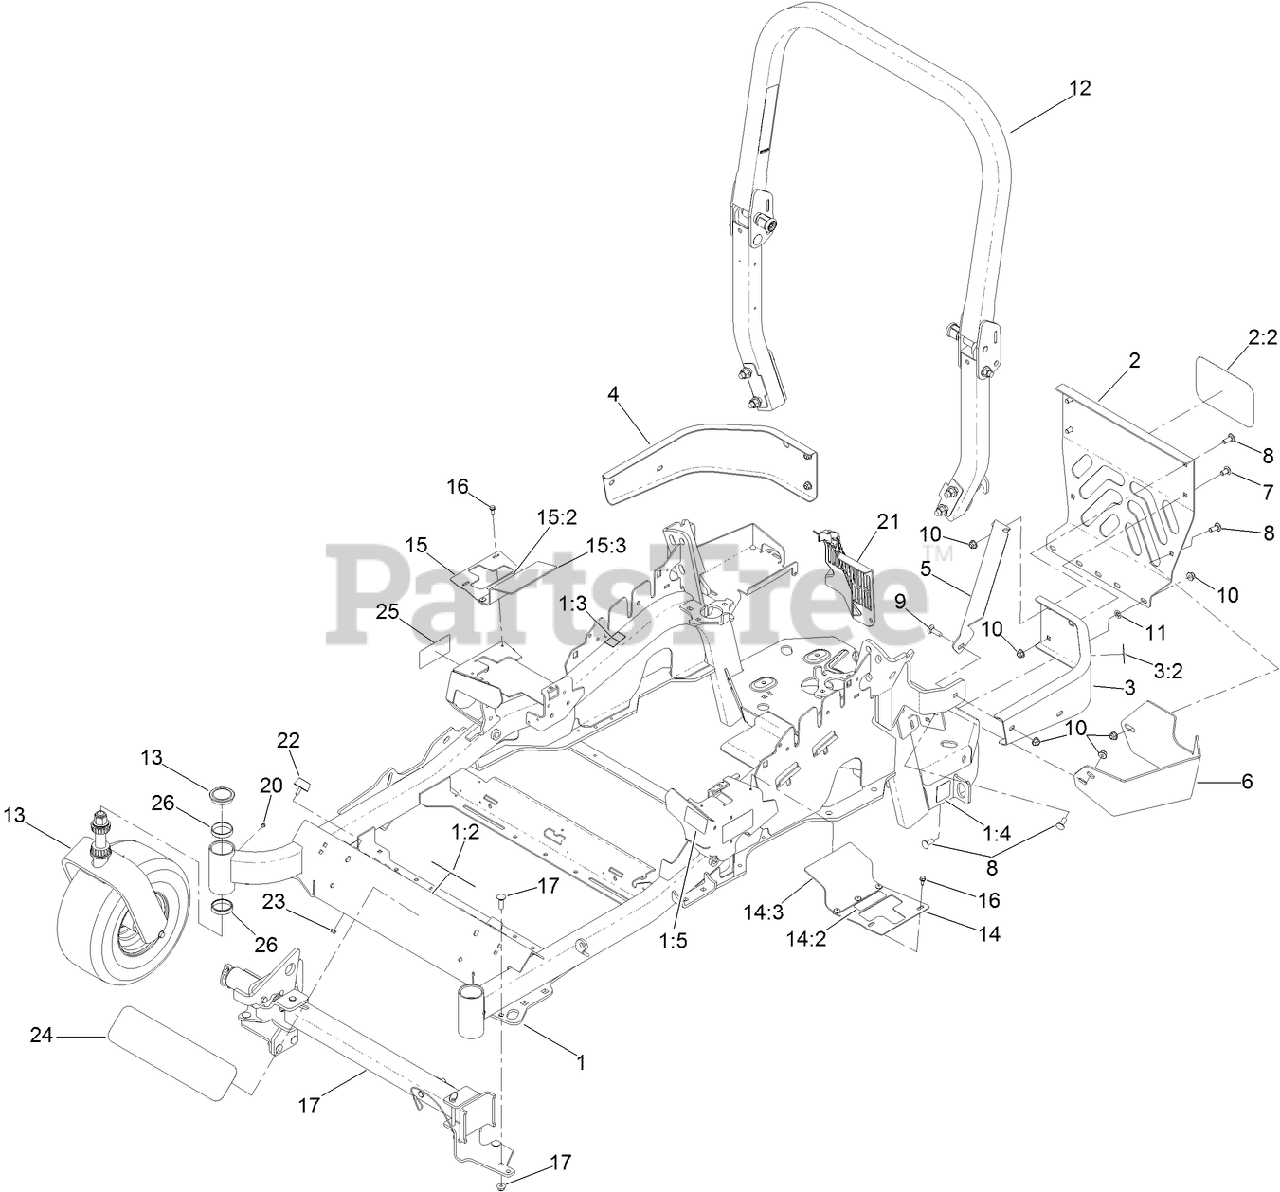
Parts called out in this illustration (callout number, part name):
1	MAIN FRAME ASM
1:2	DECAL-DANGER
1:3	DECAL-WARNING
1:4	DECAL-HAZARD, PINCHED FINGER
1:5	DECAL-FUEL FILL, CE
2	REAR GUARD ASM
2:2	DECAL
3	LH REAR BUMPER ASM
3:2	DECAL-WARNING
4	BUMPER-RH
6	GUARD-MUFFLER
7	SCREW-CARR
8	SCREW-CARR
9	BOLT-CARR
10	NUT-HF, NI
11	NUT-PUSH
12	ROPS ASM
13	Caster Wheel ASM
14	LH MOTION CONTROL COVER ASM
14:2	DECAL-CONTROL, MOTION
14:3	FLAP-RUBBER
15	RH MOTION CONTROL COVER ASM
15:2	DECAL-CONTROL, MOTION
15:3	FLAP-RUBBER
16	SCREW-HWH
17	Z STAND ASM
21	GUARD-HYDRO, REAR (RH)
22	BUMPER
23	NUT-HF
26	CUP-BEARING
